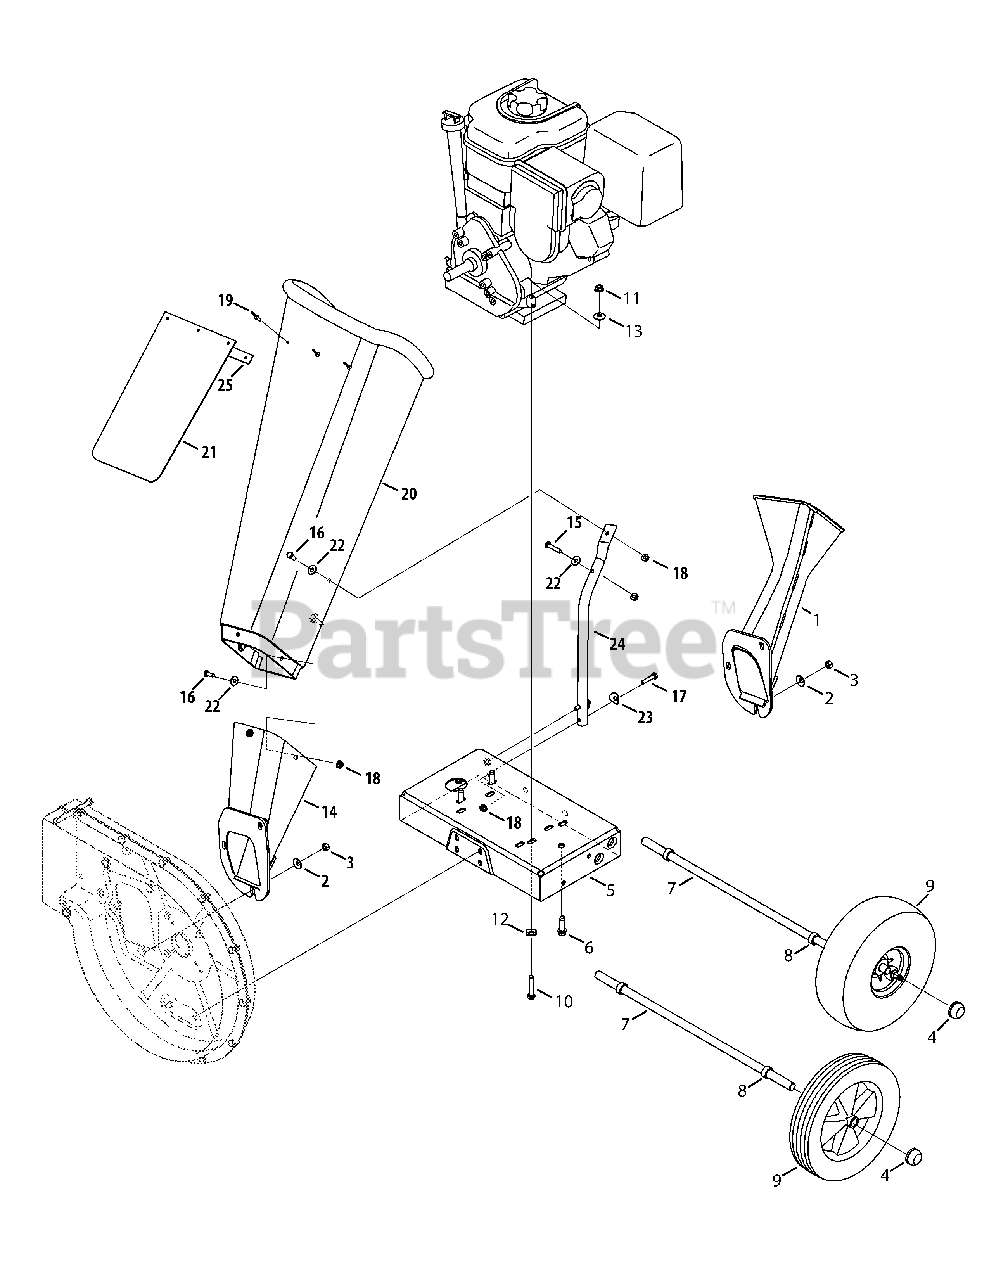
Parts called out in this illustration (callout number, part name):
1	Chipper Shredder Chute
2	Bell Washer.340 ID x.872 OD
3	Hex Nut 5/16-18
4	Push Cap
6	Screw, 3/8-16 x 1.250
7	Axle Assembly
8	Spacer
9	Wheel Comp., 10.0 x 2.5 Plastic
10	Hex Cap Screw 5/16-18 x 1.50
11	Hex Lock Nut 5/16-18
12	Bell Washer 5/16 x 1.0
13	Bell Washer.340 ID x.872 OD
14	Chipper Chute Assembly
15	Hex Cap Screw 1/4-20 x 1.25
16	Hex Cap Screw 1/4 -20 x.620
17	Hex Cap Screw, 1/4-20 x 1.250
18	Hex Lock Nut 1/4-20
19	Pop Rivet
20	Chipper Shredder Chute
21	Chute Flap
22	Flat Washer.28 ID x.74 OD
23	Washer,.320 ID x.93 OD
24	Support Brace
25	Chute Flap Strip
